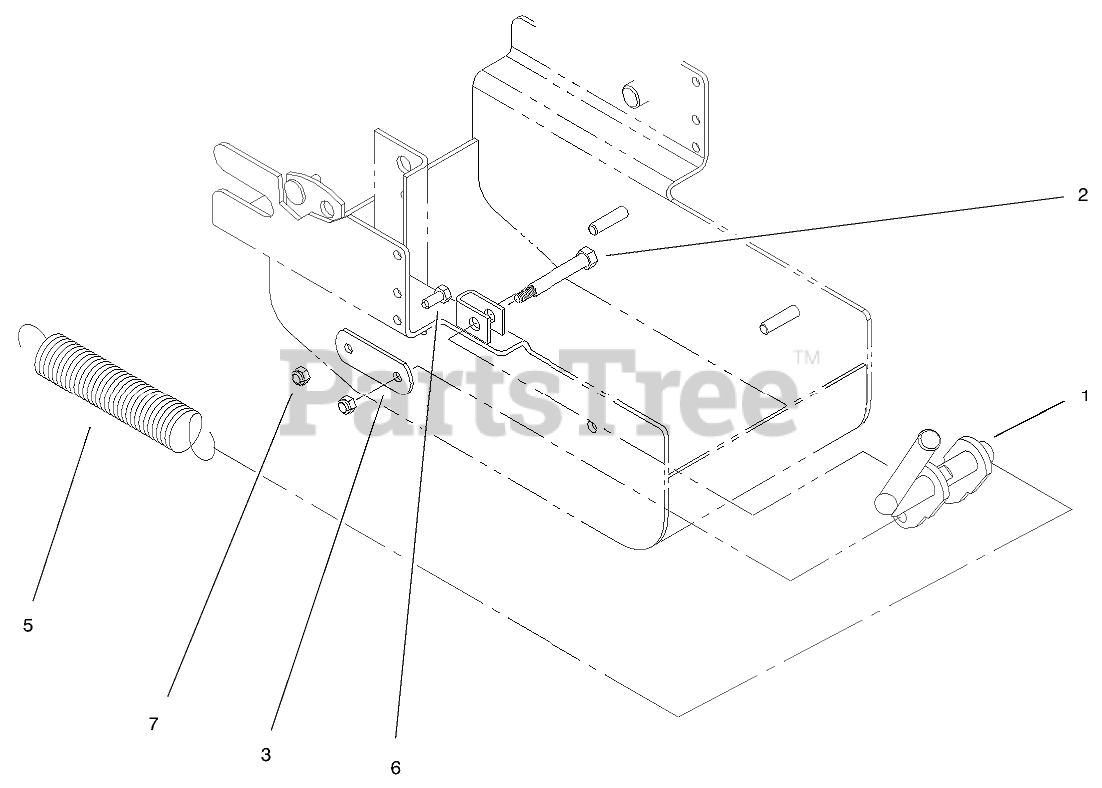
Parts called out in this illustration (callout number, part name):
2	SHOULDER BOLT
3	BRACKET-PIVOT
5	SPRING-EXT
6	SCREW-HH
7	NUT-LOCK, NI
